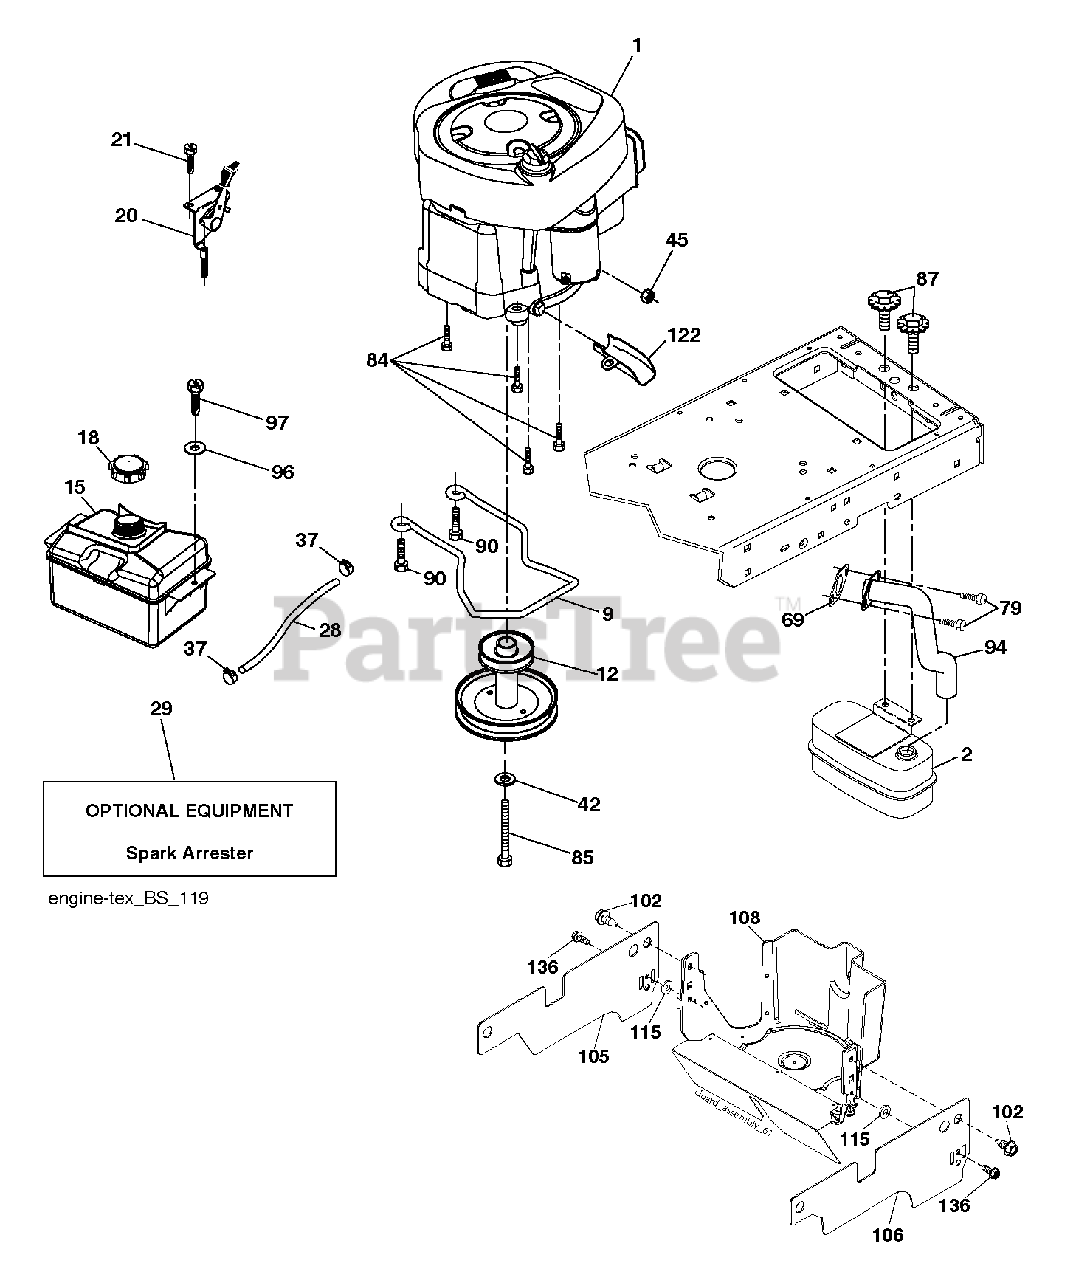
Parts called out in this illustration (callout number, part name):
2	MUFFLER.SINGLE.CYL.KOHL/B&S
9	KEEPER.BELT.ENG.4.25"2.BLT.431
12	ENGINE.PULLEY
15	RP TANK FUEL FRT 1.5 GAL
18	CAP ASM.FUEL.2.25"FR.
20	THROTTLE.COBRA.21".RSTART.BLK
21	SCREW.#10 X 0.750.BOS
28	LINE.FUEL.20
29	KIT.SPARK ARRESTOR 794945 B&S
37	HOSE CLAMP
42	WASHER 7/16 LOCK
45	NUT
69	GASKET.EXHAUST.KOHLER
79	SCREW.SOCKET HD.5/16-1
84	SCREW.3/8-16
85	BOLT.HEX.7/16-20X4.GR5.1.5BLUE
87	BOLT, 5/16-18 X 1 3/4
90	SCREW 3/8-16X1
94	EXHAUST.TUBE.B&S.28/31
97	SCREW HEXWSHR 1/4-20X3/4
102	SCREW
105	SHIELD.SIDE.LH.3842"TEX FRN.BK
106	SHIELD.SIDE.LH.3842"TEX FRN.BK
108	COVER.PULLEY.ENG.WSHL
122	EXTENSION DRAIN OIL
136	SCREW.#10 X 0.500
